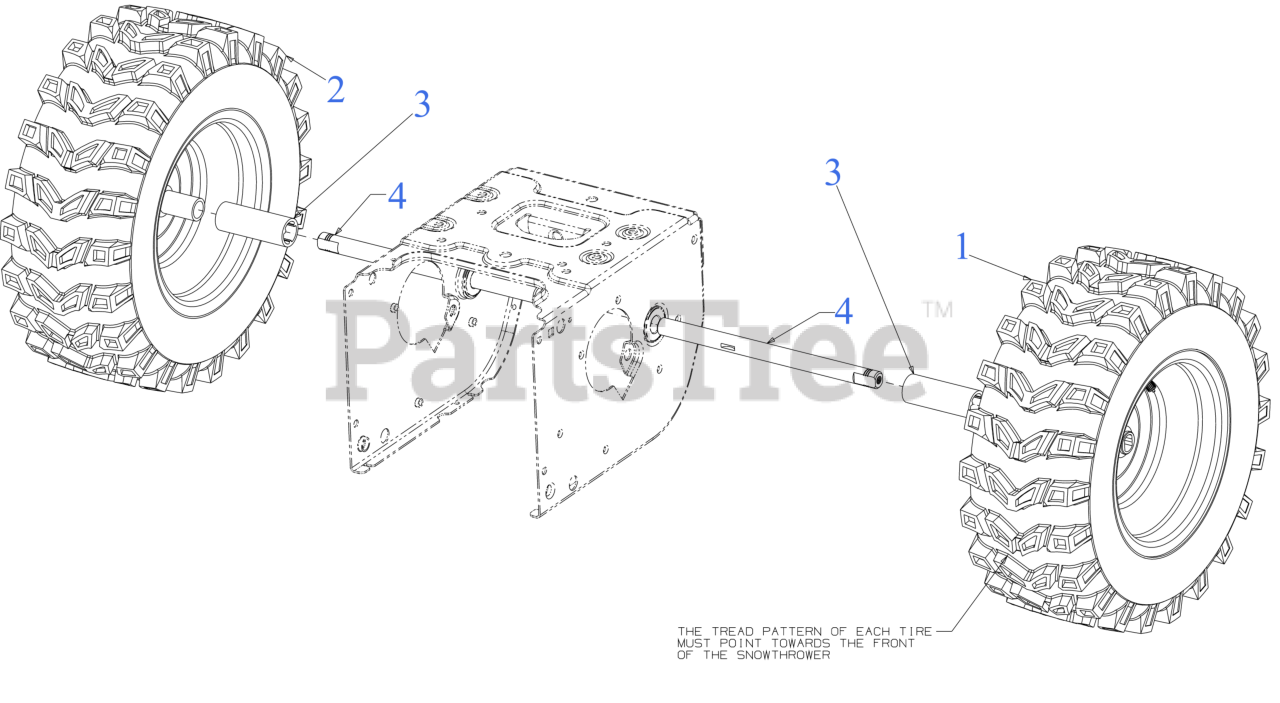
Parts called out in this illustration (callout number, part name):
1	WHEEL ASSEMBLY (16 x 6.5 x 8) (LH)
2	WHEEL ASSEMBLY (16 x 6.5 x 8) (RH)
3	SPACER 1.25 x .75 x 3.405
4	DD AXLE .75 x 11.12
